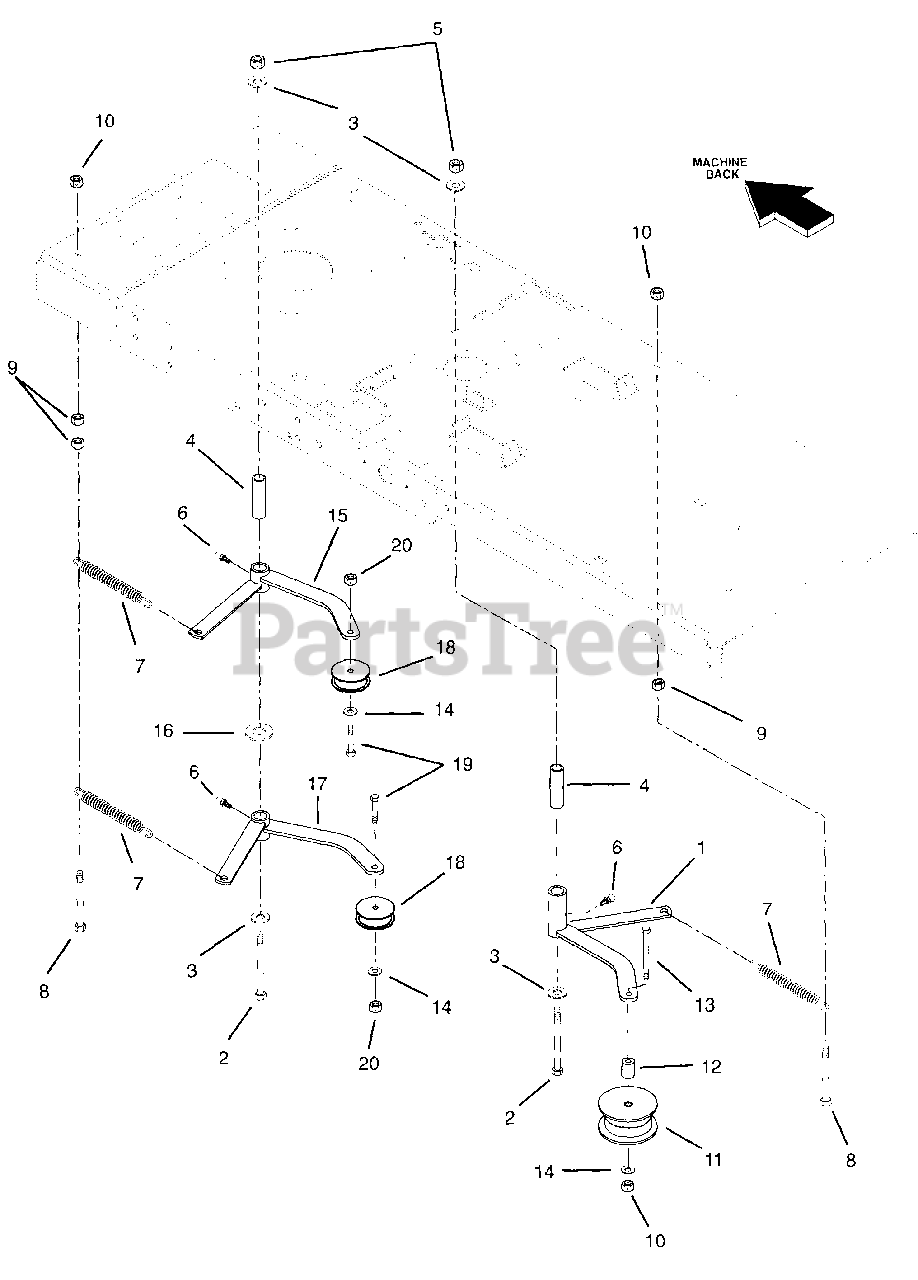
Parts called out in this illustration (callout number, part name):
1	IDLER ARM, CLUTCH TO DECK
2	@BLT-HEX .50-13X4.50 GR5 YWZC
3	@WSHR-FL-STL.563X1.38X.109YWZC
4	IDLER ARM SPACER
5	@NUT-LK-CTR .50-13 YWZC
6	FTG-LUBE .25-28X.256 YWZC
7	SPRING, EXT
8	@BLT-HEX .38-16X3.00 GR5 YWZC
9	@NUT-HEX .38-16 YWZC
10	@NUT-LK-CTR .38-16 YWZC
11	IDLER 4.0" DIA
12	SPACER, IDLER - 40"
13	@BLT-HEX .38-16X2.50 GR5 YWZC
14	@WSHR-FL-STL.406X.812X.065 YWZ
15	IDLER ARM WELD - ENG TO CLUTCH
16	WASHER, .937 X 2.25 YWZC
17	IDLER ARM WELD. TRANSAXLE
18	IDLER 3.5" DIA
19	@BLT-HEX .38-16X1.50 GR5 YWZC
20	@NUT-LK-CTR-JAM .375-16 YWZC
